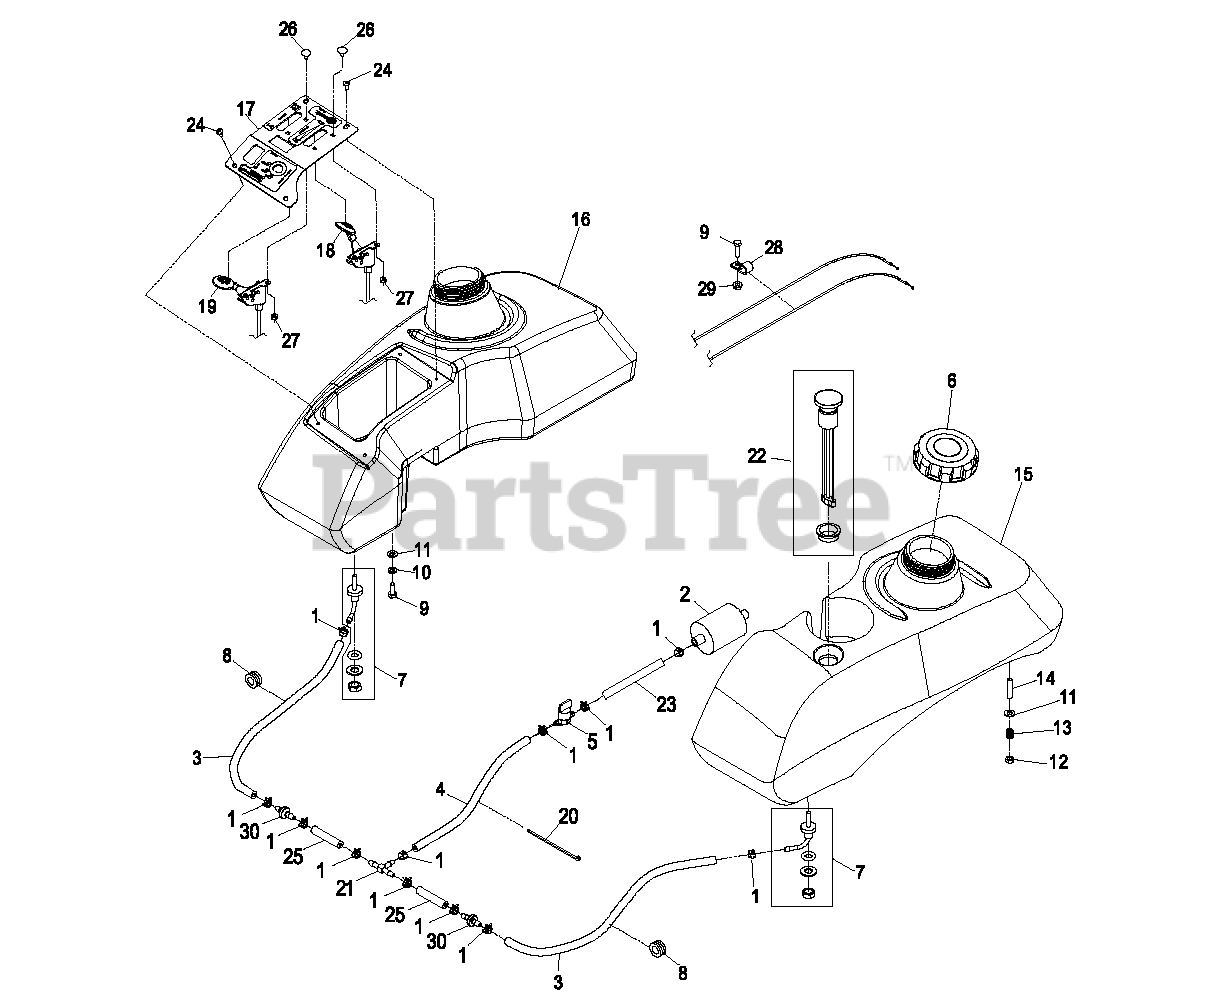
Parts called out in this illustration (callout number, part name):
2	Kohler Part No. 2405010 Fuel Filter
2	Kawaski Part No. 49019-7001 Fuel Filter
3	HOSE,FUEL
4	HOSE-FUEL
5	VALVE-FUEL
6	CAP-FUEL, GAS
7	FITTING-FUEL, BULKHEAD
7	O-RING,BULKHEAD FITTING
8	GROMMET
9	SCREW-HH
10	WASHER-LOCK
11	WASHER-PLAIN
12	NUT-LOCK, NI
13	SPRING-TANK, FUEL
14	STUD
15	KIT,FUEL TANK LH LHP
16	ASM, LHP RH FUEL TANK S.O
17	PANEL,CONTROL W/DECALS
18	CONTROL-THROTTLE
19	CONTROL,CHOKE
20	TIE-PLASTIC
21	FITTING-TEE, BARBED
22	KIT, HP FUEL GAGE REPL.
23	HOSE-FUEL
24	SCREW-PPH
25	HOSE-FUEL
26	BOLT-CARR
27	NUT-LOCK, NI
28	CLIP-LOOM
30	VALVE-CHECK, FUEL
